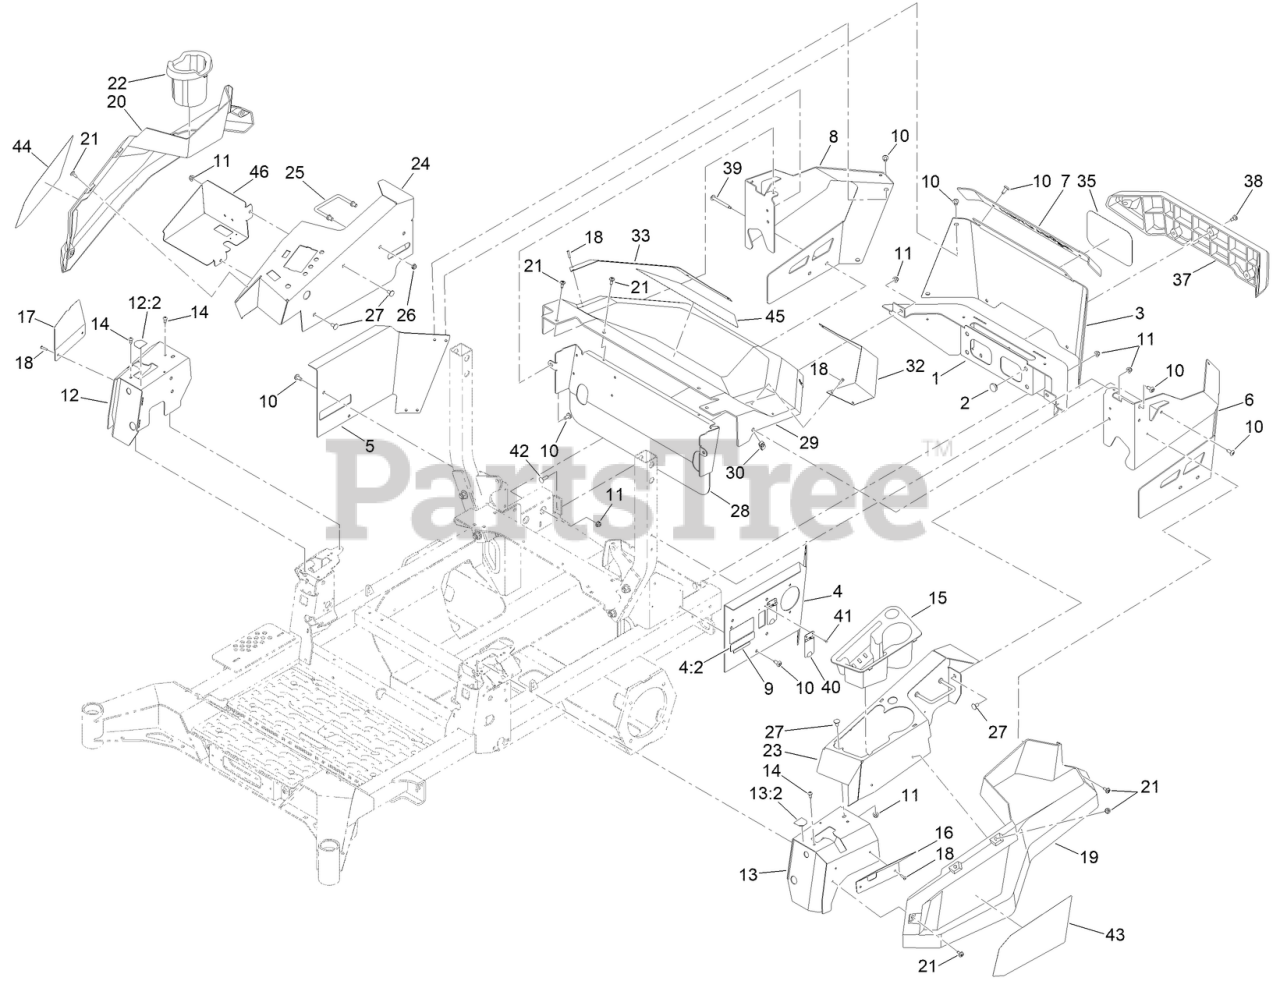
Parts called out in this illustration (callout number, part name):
1	GUARD-REAR
2	BUMPER-SEAT
3	PLATE-REAR, UPPER
4	LH REAR GUARD ASM
4:2	DECAL-SERVICE, SHUT-OFF
5	GUARD-REAR, RH
6	GUARD-REAR, LH
7	GUARD-REAR, TOP
8	GUARD-REAR, RH
9	DECAL-WARNING
11	NUT-HF, NI
12	RH COVER ASM
12:2	DECAL-CONTROL LEVER, RH
13	LH COVER ASM
13:2	DECAL-CONTROL LEVER, LH
14	SCREW-TPH THD FORM
15	CUP HOLDER
16	PLATE-COVER, LH FRONT
17	PLATE-COVER, RH FRONT
18	RIVET-TRIFOLD
19	SIDE POD, LH
20	SIDE POD, RH
21	SCREW-SHOULDER
22	CUPHOLDER-RH
23	CONSOLE-LH
24	CONSOLE-RH
25	ROD-SUPPORT, POD
27	SCREW-CARR
28	PLATE-COVER, COMPONENT
29	COVER-REAR
32	PLATE-REAR, LH
33	PLATE-REAR, RH
35	DECAL-LOGO, SILVER
37	BUMPER-REAR
38	SCREW-SHOULDER
39	SCREW-TORX
40	PLATE-COVER, SPRING
41	RIVET
42	SCREW-CARR
43	DECAL-POD, LH
44	DECAL-POD, RH
45	DECAL-HYPERCELL
46	PLATE-COVER, ELECTRICAL
